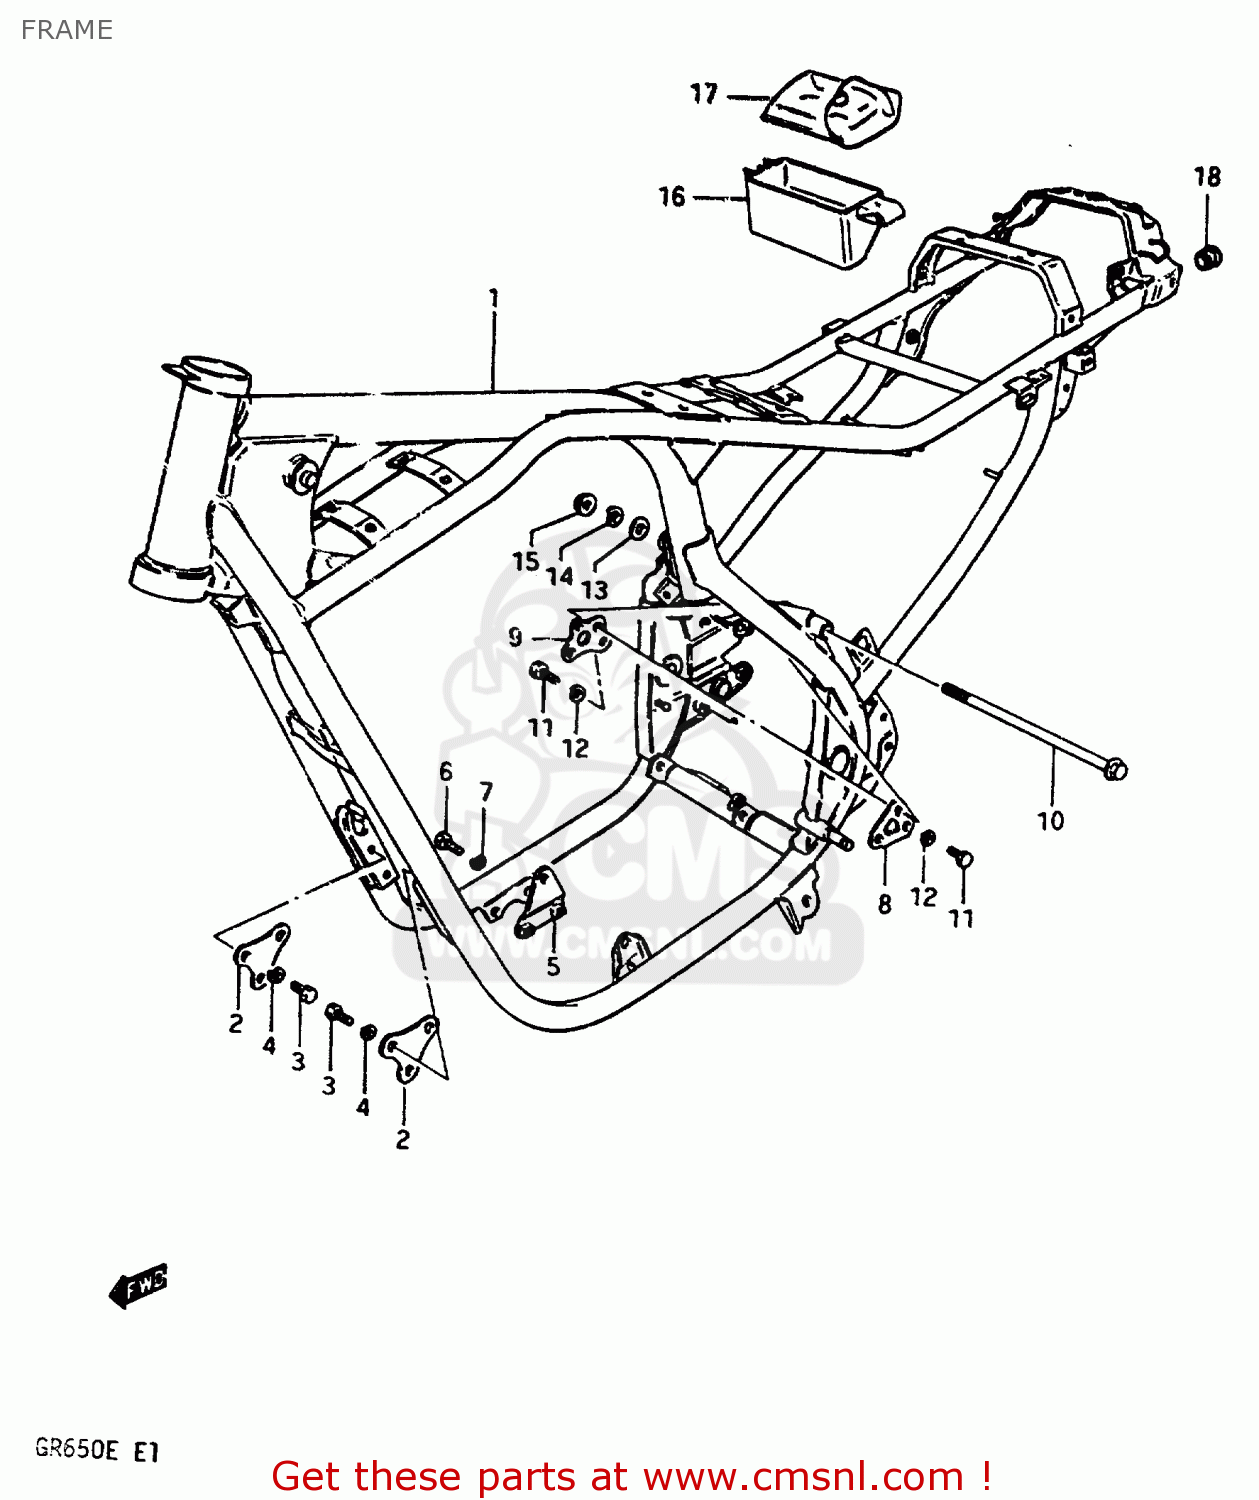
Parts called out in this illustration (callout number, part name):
1	FRAME (BLACK)
2	PLATE,ENGINE MOUNTING NO
3	BOLT
4	LOCK WASHER
5	PLATE,ENGINE MOUNTING NO
6	BOLT
7	LOCK WASHER
8	PLATE,ENGINE MOUNTING NO
9	PLATE,ENGINE MOUNTING NO
10	BOLT
11	BOLT
12	LOCK WASHER
13	WASHER,8.5X16X
14	LOCK WASHER
15	NUT
16	HOLDER,TOOL
17	TOOL SET
18	CAP(OD:26)
